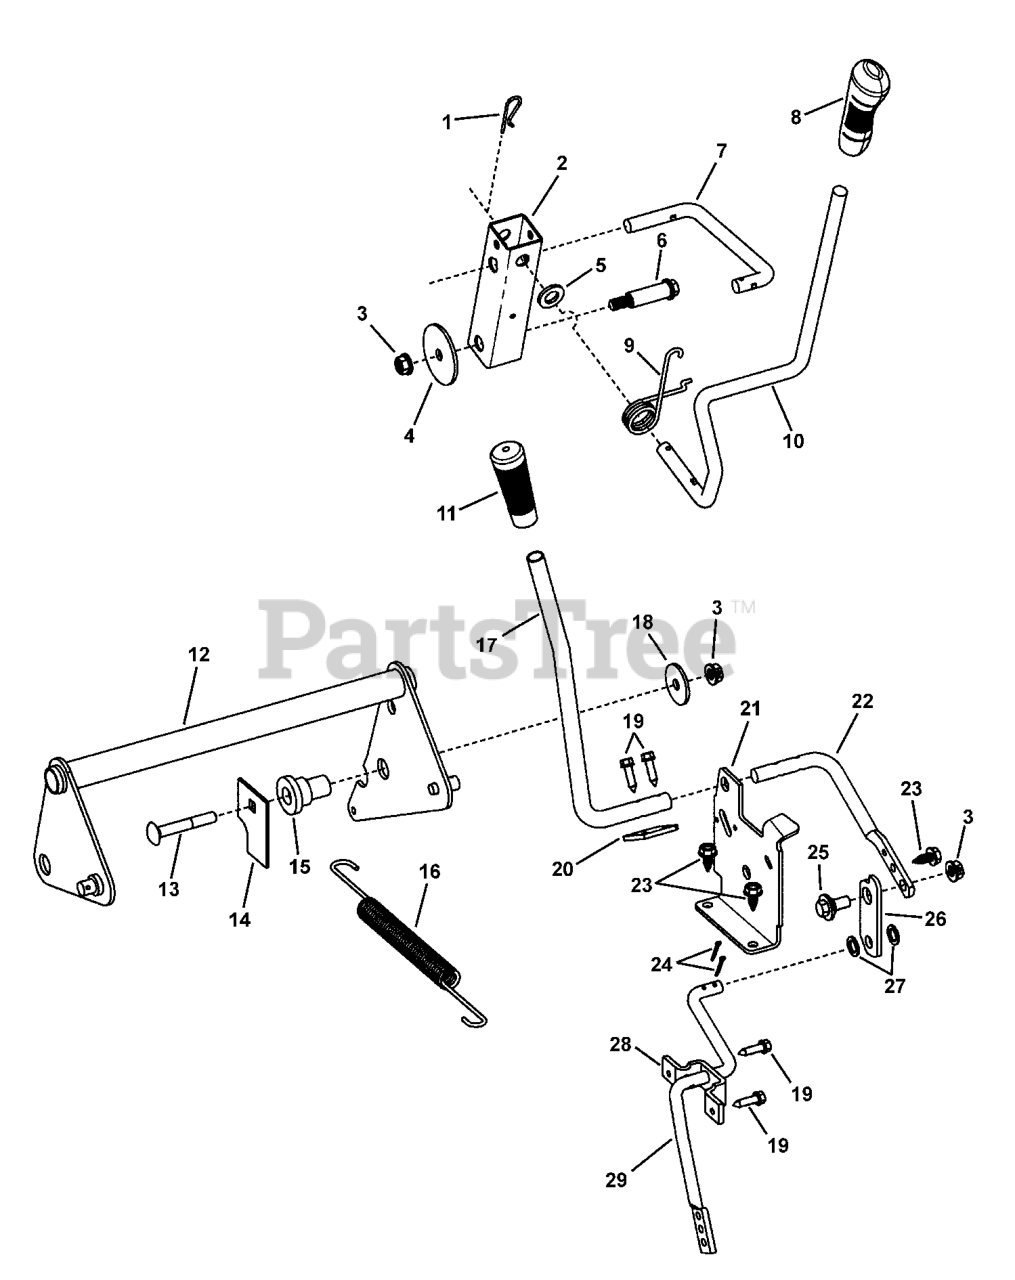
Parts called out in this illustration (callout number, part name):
1	HAIR PIN, .56D-.092T
2	BRACKET - PIVOT
3	NUT, HEX FLANGE, 3/8-16 NC
4	HER PLAIN .406 X 2.25
5	HER - FLAT, 1.0"OD X 0.550"
6	SHOULDER BOLT, 1.563L X 0.75D X 9/16 X 3/8-16
7	LINK - LIFT HANDLE
8	GRIP
9	SPRING - TORSION
10	HANDLE - LIFT
11	GRIP, .50 SHAFT, TAPERED
12	LIFTER ASSY (WELDMENT)
13	RHSSNB,3/8CX2-1/2
14	PLATE STIFFENING
15	SPACER - LIFTER PIVOT
16	SPRING, EXTENSION
17	HANDLE, PTO
18	HER 1-1/2 OD
19	THD FORMING HES HD SCREW, 1 X 1/4-20 STEP TAPER
20	PADDLE - SWITCH
21	BRACKET - PTO
22	LEVER - PTO
23	CAPSCREW 5/16-18
24	PIN - COTTER, 0.75 X 0.090
25	SHOULDER BOLT, 0.75 X 0.60 X 3/8-16
27	HER - FLAT, 0.72OD X 0.469ID X 16GA
28	BRACKET - BELLCRANK
29	CRANK - PTO
